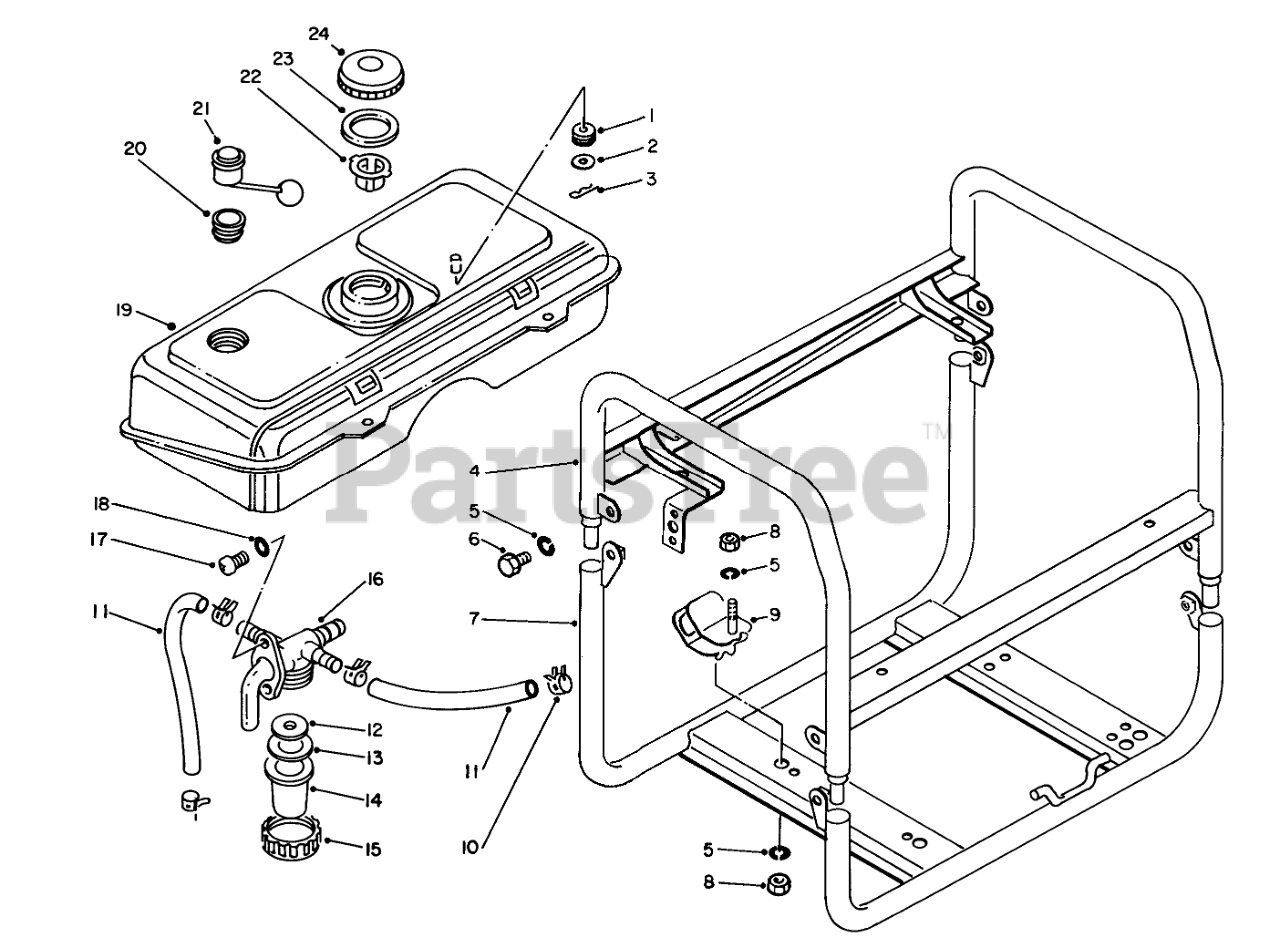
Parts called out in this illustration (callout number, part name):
1	CUSHION
2	WASHER
4	Frame-Upper
5	WASHER-LOCK
7	Screw
9	Mount-Engine
12	FILTER
13	GASKET
16	Cock Assembly-Fuel (Incl. Ref. #12-15)
17	Screw
18	Lockwasher
19	Tank-Fuel
20	Gasket
21	Gauge Assembly-Fuel (Incl. Ref. #20)
22	FILTER
23	GASKET
24	Cap (Incl. Ref. #23)
